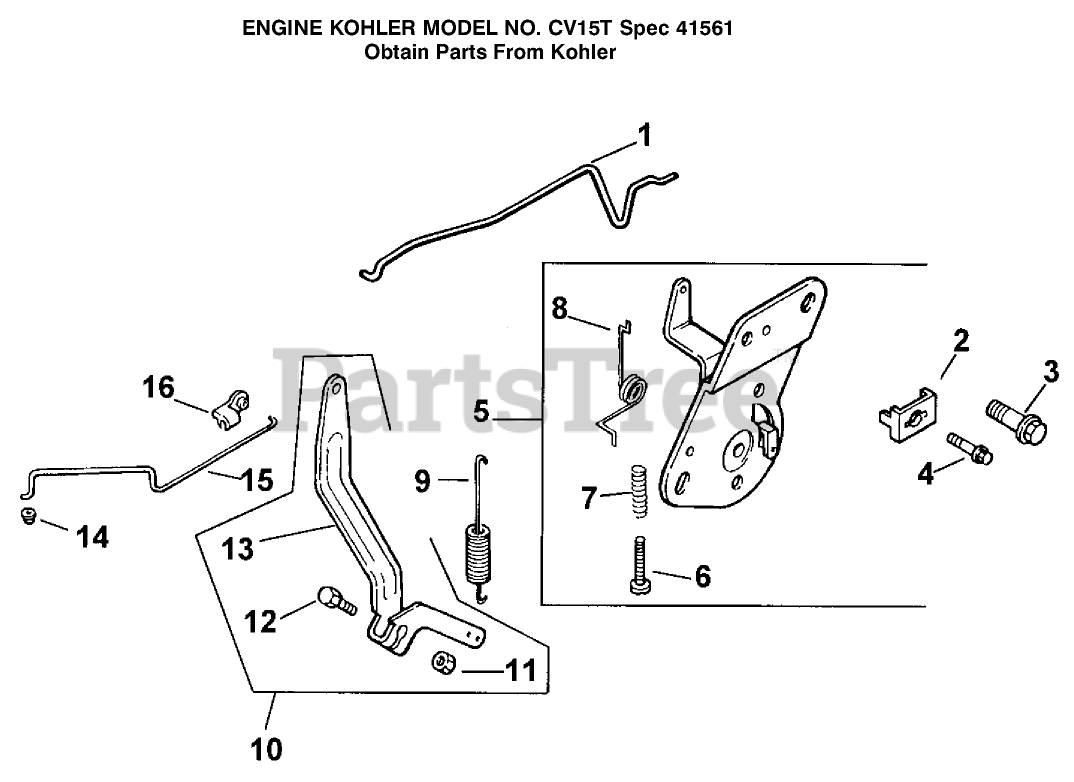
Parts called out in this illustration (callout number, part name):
1	Linkage Choke
2	Clamp
3	Screw Socket
4	Screw
5	Control-Speed
6	Screw
7	Spring
8	Spring Choke
9	Spring-Governor
10	Kit-Governor Lever (Incl. Ref.#11-13)
11	Nut
12	Bolt
13	Lever-Governor
14	Bushing-Linkage
15	Linkage-Throttle
16	Bushing-Linkage
